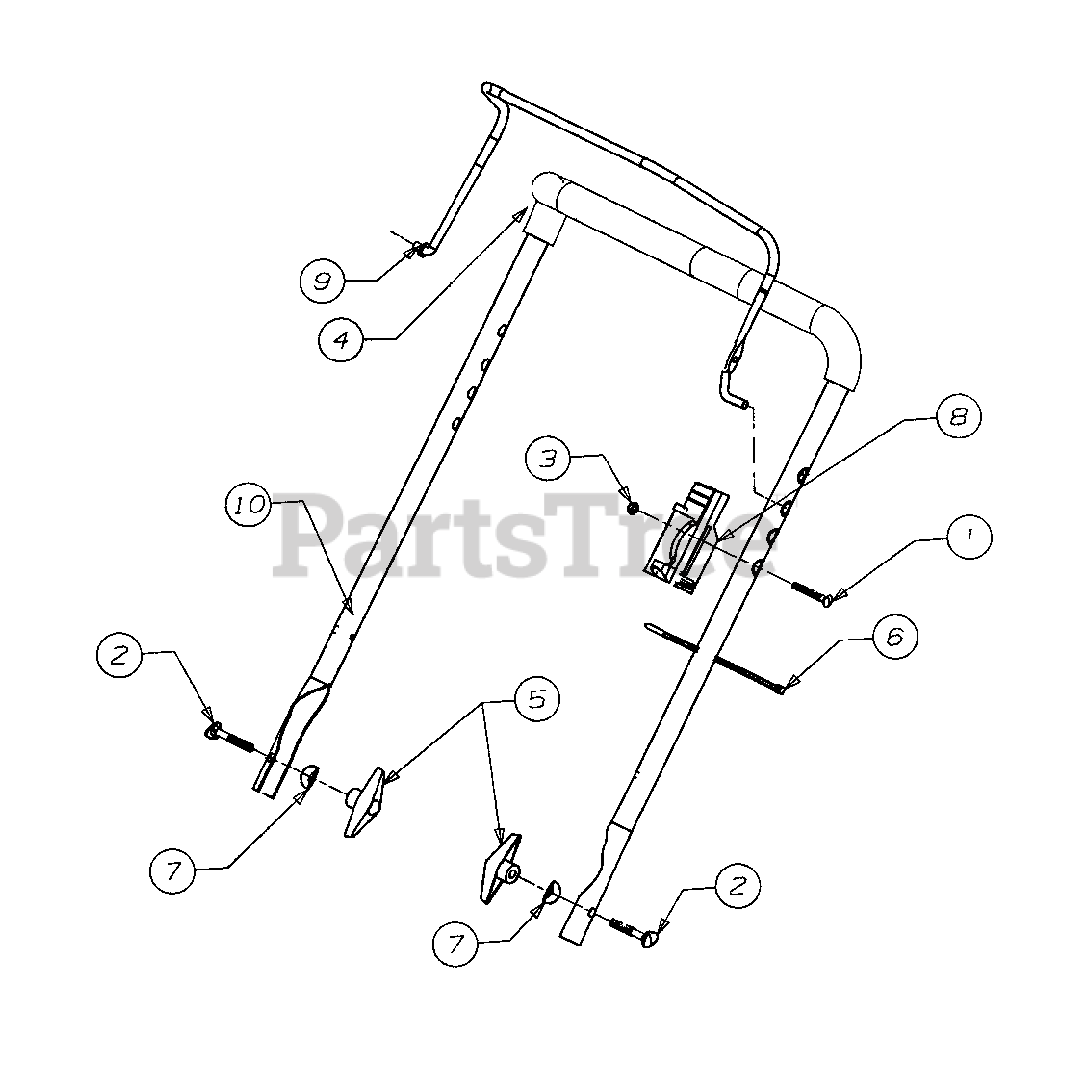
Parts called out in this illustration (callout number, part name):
1	Oval C-Sink L Screw
2	Carriage Bolt
3	Insul. Lock Nut
4	Grip, Foam
5	Knob, Handle
6	Tie, Cable
7	Washer, Saddle
8	Body-Lever Control
